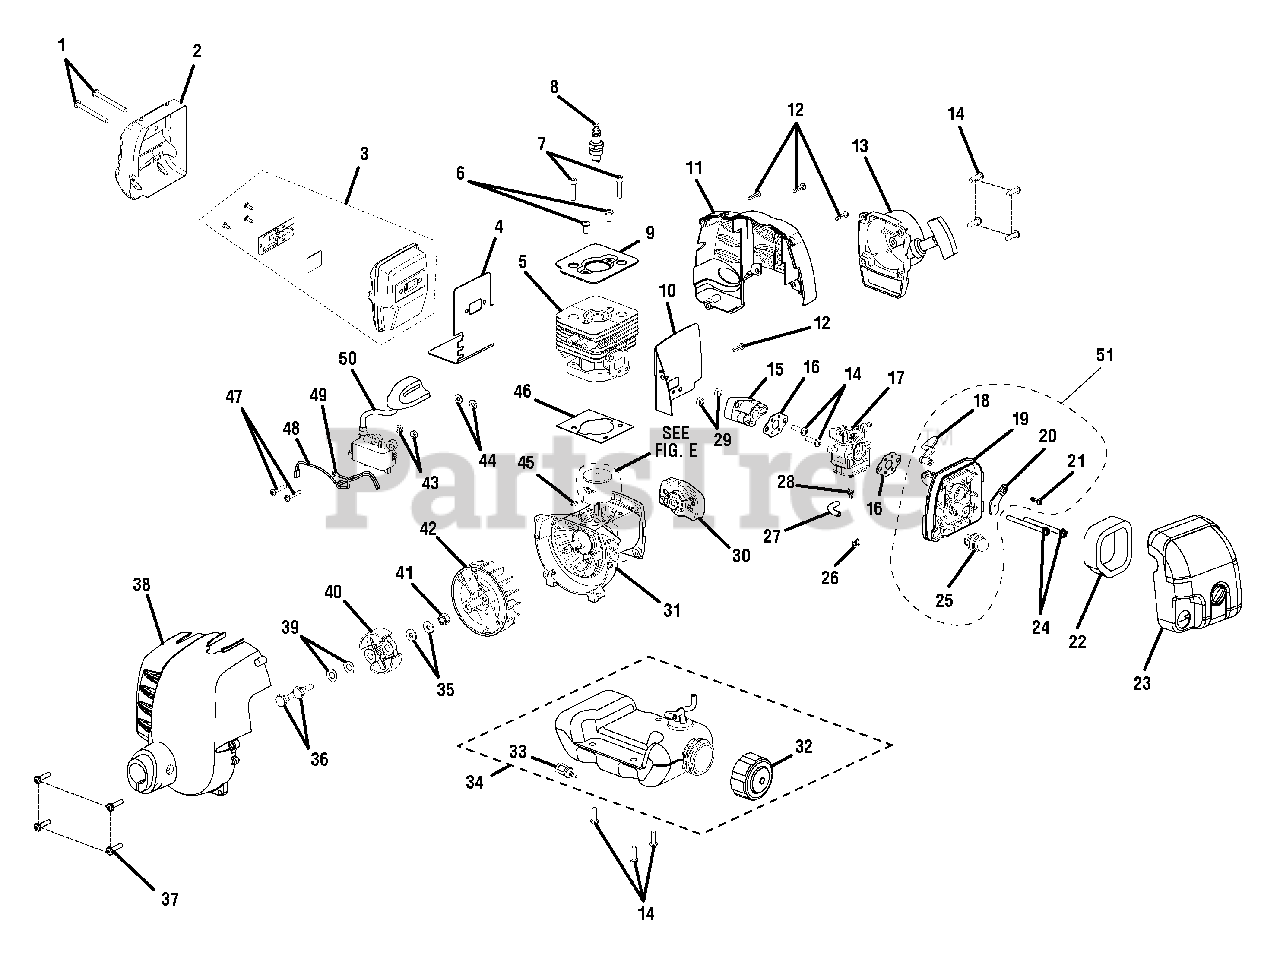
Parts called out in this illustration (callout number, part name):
1	SCREW (M5 X 50 mm TORX SLOTTED RECESSED PAN HD.)
2	HEAT SHIELD
3	MUFFLER ASSEMBLY
4	MUFFLER GASKET
5	CYLINDER
6	SCREW (M5 X 10 in. TORX RECESSED PAN HD.)
7	SCREW (M5 X 22 mm SOCKET HD.)
8	SPARK PLUG
9	CYLINDER PLATE
10	INSULATOR GASKET
11	ENGINE HOUSING, REAR
12	SCREW (M4 X 16 mm TORX RECESSED PAN HD.)
13	STARTER RECOIL ASSEMBLY
14	SCREW (M5 X 16 mm Torx SLOTTED RECESSED PAN HD.)
15	HEAT DAM INSULATOR
16	CARBURETOR GASKET
17	CARBURETOR ASSEMBLY
18	CHOKE LEVER
19	CARBURETOR PLATE
20	CHOKE PLATE
21	SCREW (M4 X 12 mm SLOTTED RECESSED PAN HD.)
23	COVER ASSEMBLY
24	SCREW (M5 X 60 mm, SLOTTED RECESSED PAN HD. MACHINE)
25	PRIMER ASSEMBLY
26	HOSE CLIP
27	FUEL LINE
28	HOSE CLIP
29	NUT (M5 x .8 mm)
30	PULLEY ASSEMBLY
31	CRANKCASE ASSEMBLY
32	FUEL CAP ASSEMBLY
33	FUEL FILTER
34	FUEL TANK ASSEMBLY
36	CLUTCH SCREW
37	SCREW (M5 X 20 mm TORX SLOTTED RECESSED PAN HD.)
38	FRONT HOUSING ASSEMBLY
39	CURVED WASHER
40	CLUTCH ASSEMBLY
41	ROTOR NUT
43	IGNITION COIL SPACER
44	WASHER (3/16 x 3/64)
45	WOODRUFF KEY (10 mm X 3 mm)
47	SCREW (M4 X 22 mm TORX SLOTTED RECESSED PAN HD.)
48	LEAD ASSEMBLY, BLACK
49	LEAD ASSEMBLY, RED
50	COIL BOOT ASSEMBLY
51	FILTER HOUSING ASSEMBLY
